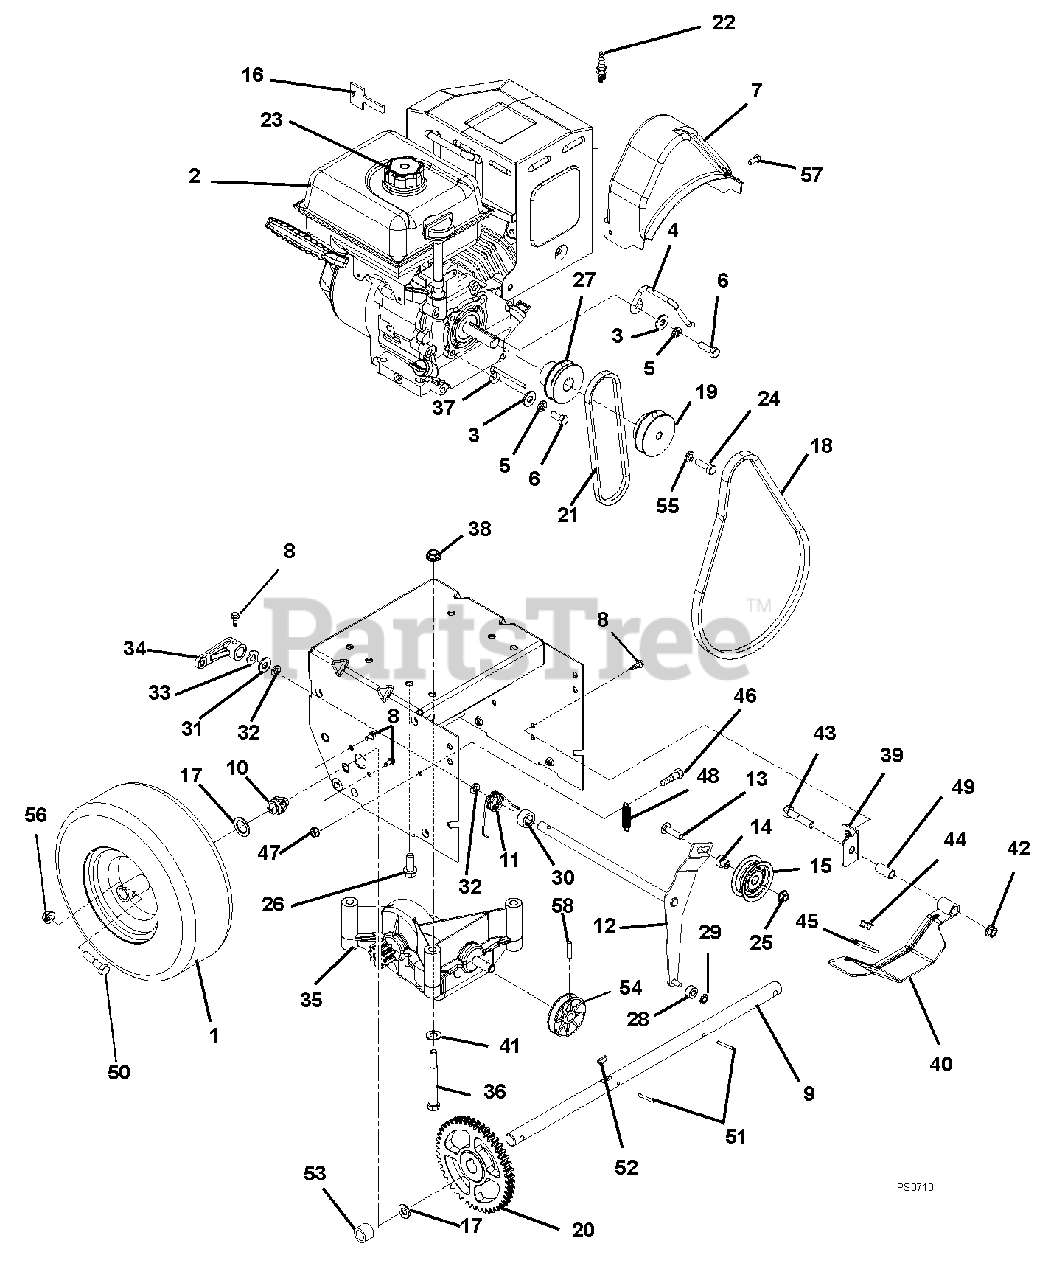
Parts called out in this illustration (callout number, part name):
1	TIRE/WHEEL, 13X4.10-6 K398A
2	ENGINE,LCT STORMFORCE 208 RECL
3	@WSHR-FL-STL.38X.875X.083 YWZC
4	FINGER, BELT
5	WSHR-LK .312X.097 HVY YWZC
6	BLT-HEX .31-24X.75 YWZC GR5
7	COVER, BELT
8	SCR-TAP .25-20X.50 HWH TR YWZ
9	AXLE, 939,XXX W/LG TIRES
10	BSHG .75X1.125X.65
11	SG-TORS .067X.88
12	WELDMENT, ATTACHMENT IDLER ARM
13	@BLT-RHDSHSQNK.31-18X1.25 G5YZ
14	SPCR, BRG .315X.50X.688X.281
15	IDLER
16	KEY, PUSH/PULL LCT (2/PACKAGE)
17	WSHR-FL-STL.754X1.125X.062YWZC
18	V-BELT, 4L-RAW EDGE
19	SHEAVE, ENGINE
20	GEAR, AXLE 45T
21	V-BELT, 3L-STRETCH FIT
22	PLUG, SPARK
23	CAP, FUEL TANK BLACK
24	BLT-HEX .38-24X1.0 YWZC GR5
25	@NUT-LK-TOP-FLG .31-18 YWZC
26	SCR-TAP .38-16X1.0 HWH YZ W/VT
27	SHEAVE, DRIVE
28	BSHG,SLV .270 X .750 X .250
29	RG-RTNG-EXT .250X.010
30	BSHG-SLV .510X.751X.475
31	WSHR-FL-STL .52X.827X.062 YWZC
32	BUSHING, POLYLINER-.50 SNAPIN
33	WSHR-WAVE .50X.75X.015 .13FRHT
34	ARM, CLUTCH - ATTACHMENT
35	TRANSMISSION, GT H0 W/O PULLEY
36	@BLT-HEX .38-16X3.50 GR5 YWZC
37	BELT FINGER
38	NUT-LK-CTR-FLG .38-16 YWZC
39	BRACKET, MOUNT - BRAKE
40	ARM, BRAKE
41	@WSHR-FL-STL.406X.812X.065 YWZ
42	@NUT-LK-TOP-FLG .38-16 YWZC
43	@BLT-HEX .38-16X1.75 GR5 YWZC
44	RVT-POP .187 YZ
45	PAD, BRAKE
46	BLT-SHLDR .31X.50 .25-20X.438
47	@NUT-SPNLK-FLG .25-20 YWZC
48	SG-TENS .06X.46X2.00
49	BSHG-SLV .385X.500X1.045
50	@BLT-HEX .31-18X1.50 GR5 YWZC
51	PIN-ROLL .188X1.25
52	KEY-WDRF .25X.750X.313 SAE91
53	BSHG-SLV .766 X 1.065 X 1.289
54	PULLEY, COMPOSITE 3L INPUT
55	@WSHR-LK .38X.094 REG YWZC
56	@NUT-LK-CTR-FLG .31-18 YZ GR F
57	SCR-TAP .25-20X.50 LGHWH TR YZ
58	PIN-ROLL, 5MMX26MM
